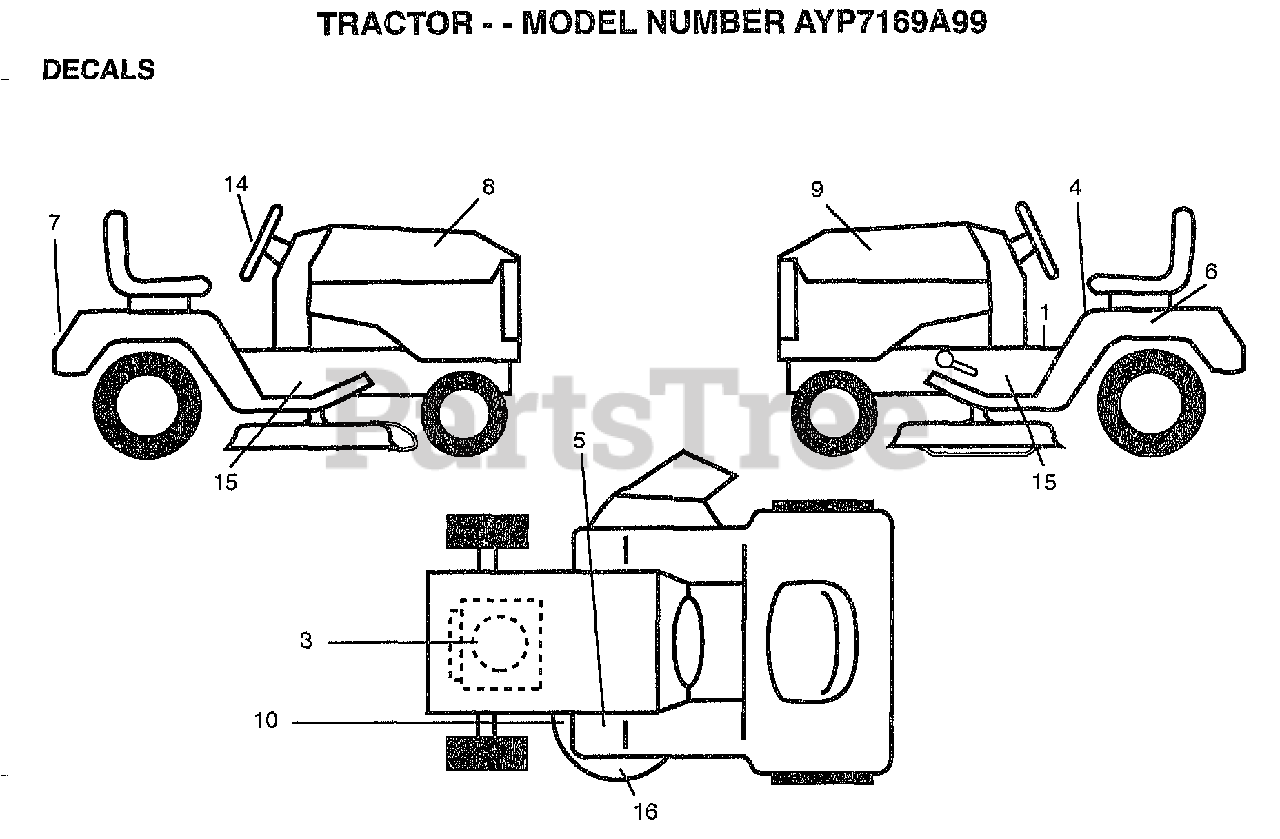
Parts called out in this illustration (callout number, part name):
1	"DECAL DASH,OPER."
3	DECAL.ENGINE
4	"DECAL DANGER,FEND"
6	DECAL.BATRY.3-3908
8	DECAL.HOOD.RH
9	DECAL.HOOD.LH
10	"DECAL-SCHEM,BELT"
14	DECAL.INS.STRG.WL
15	DECAL CHASSIS WIZ
16	DECAL DECK WIZ +
